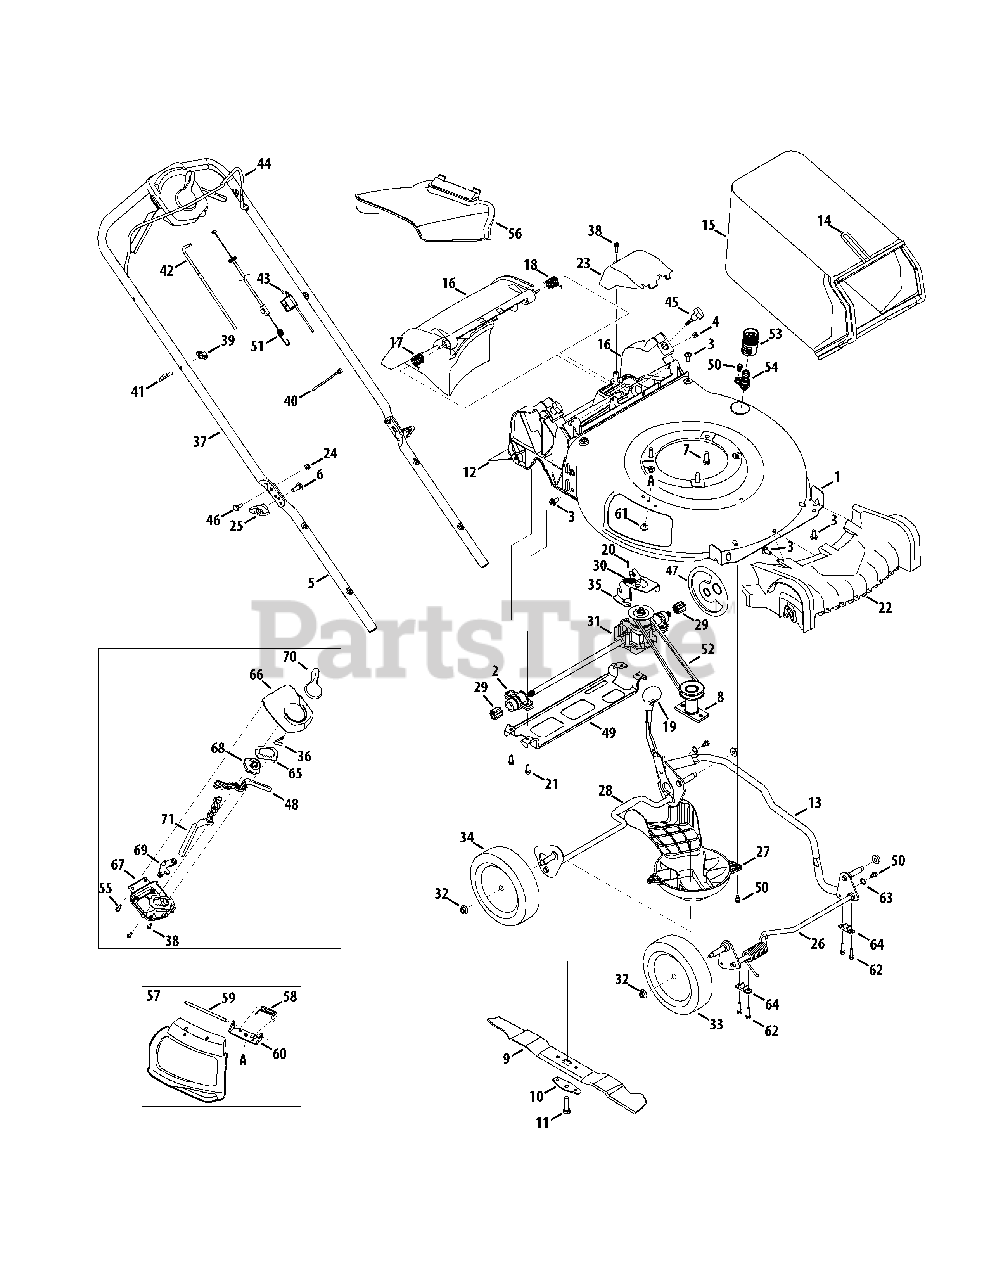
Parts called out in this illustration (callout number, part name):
1	Deck , 21"
2	Bearing Assembly
3	Screw, 5/16-14 x .750
4	Nut, Sq., 1/4-20
5	Lower Handle
6	Carriage Screw ,5/16-18
7	Screw, 3/8-16 x 1.00
8	Blade Adapter
9	Mulching Blade
10	Blade Bell Support
11	Screw, 3/8-24 x 1.50
12	Trailing Shield
13	Cross Bracket
14	Grass Catcher Frame
15	Grass Bag
16	Rear Discharge Door Assembly
17	Torsion Spring - RH
18	Torsion Spring - LH
19	Adjustment Lever Knob
20	Screw, Hex Washer, .159 x .43
21	Screw, 1/4-15 x 1.25
22	Front Cover
23	Transmission Cover
24	Nut, Flange Lock, 1/4-20
26	Front Axle Assembly
27	Engine Baffle
28	Rear Axle Assembly
29	Spur Gear, 10T
30	Exten. Spring, 2.405
31	Transmission Assembly
32	Flange Lock Nut, 3/8-16
33	Front Wheel
34	Rear Wheel
35	Transmission Bracket
38	Screw, 1/4-15 x .750
40	Cable Tie
41	Rope Guide
42	Drive Cable
43	Control Cable
44	Blade Control
45	Wing Nut
46	Sldr. Screw, .375 x .126 x 1/4-20
47	Wheel Dust Cover
48	Control Lever LH
49	Rear Support Bracket
50	Scr., Shldr., 1/4-20 x .50
51	Speed Adjustment Cable
53	Water Nozzle Adapter
54	Water Nozzle
55	Scr., Shldr, 1/4-15 x .970
56	Side Discharge Chute
57	Mulch Plug (Incl. 58-60)
58	Torsion Spring
60	Chute Deflector Bracket
61	Screw, 1/4-20 x .500
62	Screw, 1/4-15 x 1.000
63	Wash., Wave, .385 ID x .598 OD
64	Bushing, Lock, .505 Dia. X .62
65	Cable Adjust Plate
66	Upper Housing
67	Lower Housing
68	Speed Adjust Actuator
69	Drive Cable Actuator
70	Speed Select Lever
71	Control Lever RH
